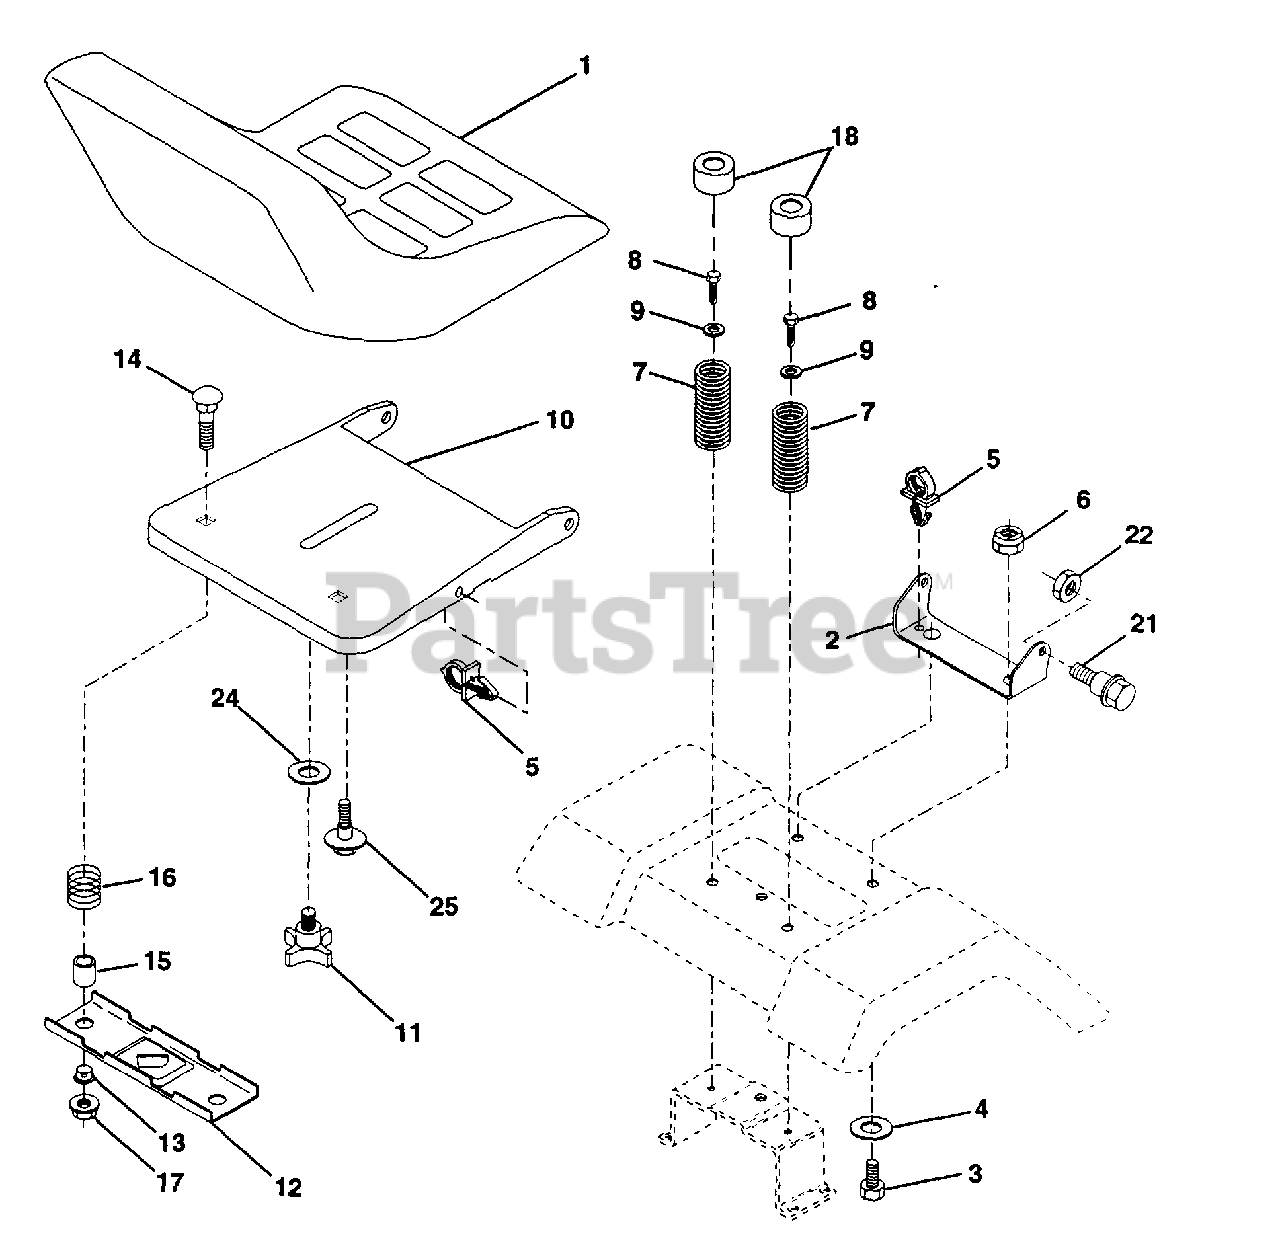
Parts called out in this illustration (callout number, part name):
1	Seat
2	Bracket Pivot Seat 8 720
3	Bolt Fin Hex 3/8-16unc X 1
4	Washer 13/32 X 1 X 10 Ga
5	Clip Push-In
6	Nut Hex w/Ins. 3/8-16 Unc
7	Spring Seat Cprsn 2 250 Blk Zi
8	Screw Thdrol 3/8-16 X 1 Ty-tt
9	Washer 13/32 X 1 X 14 Ga.
10	Pan Seat
11	Knob Seat 1/2-13 UNC Blk
12	Bracket Mounting Switch
13	Bushing Snap Blk Nyl 50 Id
14	Bolt Rdhd Sqnk 1/4-20 x 1-1/2
15	Spacer Split 28 x 96 Yel Zinc
16	Spring Cprsn 1 27 Blk Pnt
17	Nut Lock 1/4 Lge Flg Gr 5 Zinc
18	Cap Spring Seat
21	Bolt Shoulder 5/16-18 Unc
22	Nut Hex Lock W/Ins 5/16-18
24	Washer 17/32 X 1-3/16 X 12 Ga.
25	Bolt Shoulder 5/16-18 X 62
